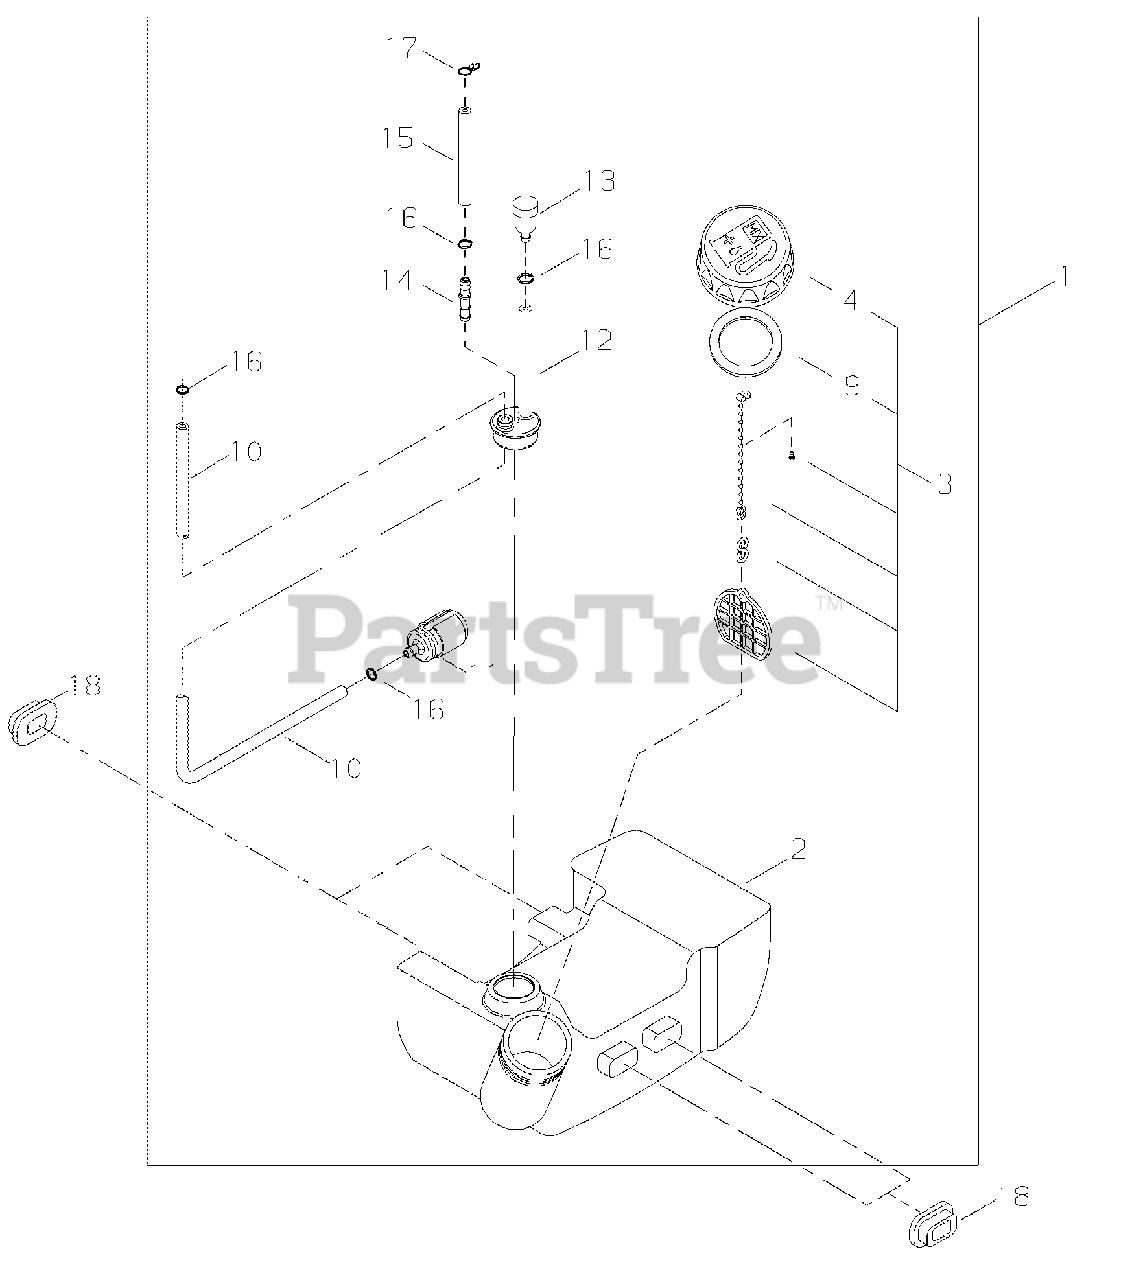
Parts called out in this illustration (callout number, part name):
1	FUEL TANK ASSY
2	TANK, FUEL
3	CAP ASSY
4	CAP, FUEL
9	GASKET, CAP
10	PIPE - FUEL
11	FILTER, FUEL
12	GROMMET
13	ELEMENT, BREATHER
14	CONNECTOR, PIPE
15	PIPE
16	RING, RETAINING - 6
17	CLIP - SPRING
18	CUSHION, FUEL TANK
